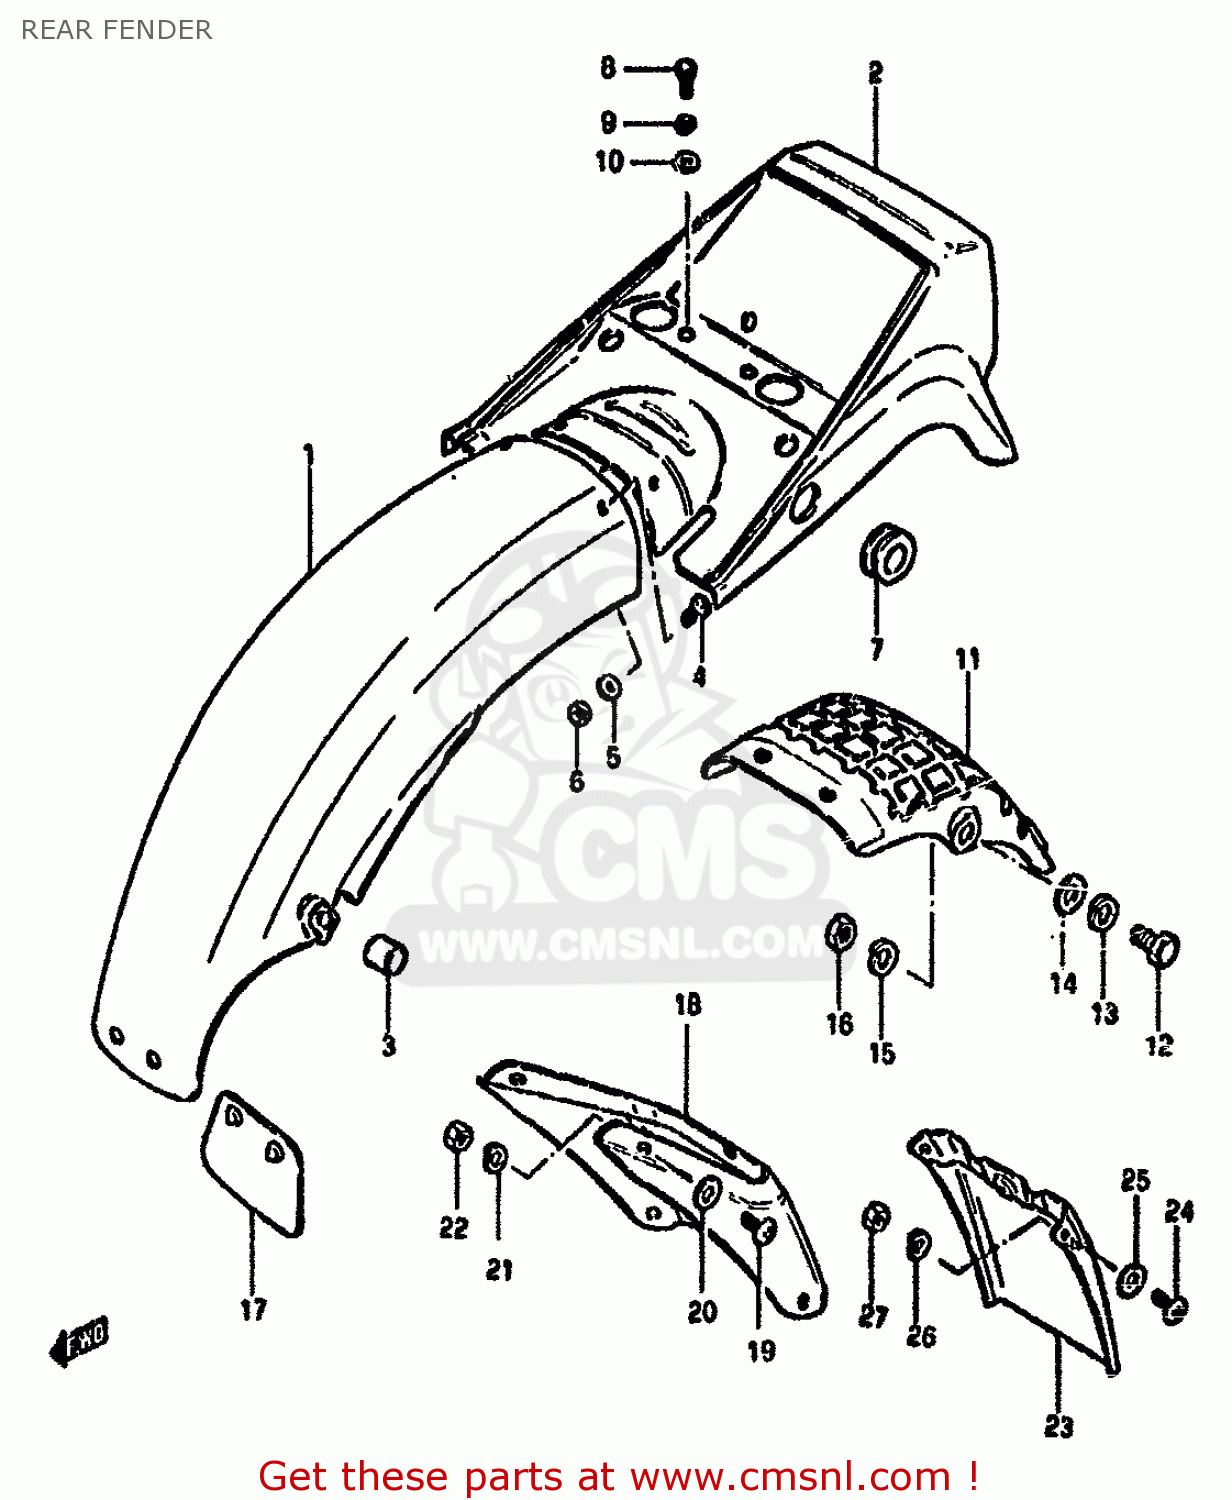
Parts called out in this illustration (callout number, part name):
1	FENDER,REAR
2	BODY,REAR FENDER,REAR
3	CUSHION
4	SCREW M5X12 DIN 7985/N
5	WASHER (5.5X16X1.2)
6	NUT
7	GROMMET,SEAT LOCK HOLE
8	BOLT
9	LOCK WASHER
10	WASHER
11	REINFORCEMENT
12	BOLT
13	LOCK WASHER
14	WASHER
15	LOCK WASHER
16	NUT
17	GUIDE,RR FENDER MUD
18	EXTENSION,REAR FENDER
19	SCREW 6X12
20	WASHER (6.5X18X1.6)
21	LOCK WASHER
22	NUT
23	MUDGUARD,EXTENSION
24	SCREW 6X12
25	WASHER (6.5X18X1.6)
26	LOCK WASHER
27	NUT
